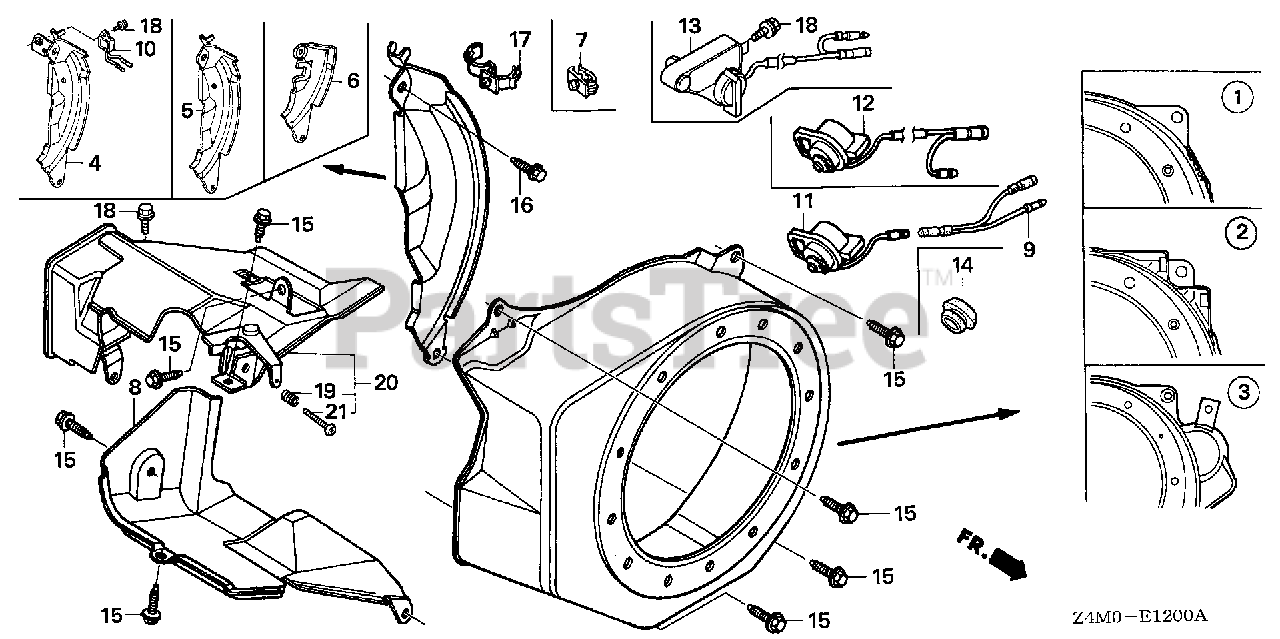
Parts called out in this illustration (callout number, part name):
1	COVER, FAN *NH1* (Honda Code 4212437). (BLACK)
1	COVER, FAN *R280* (Honda Code 7351950). (POWER RED)
4	PLATE, SIDE (OIL ALERT)
8	SHROUD
10	ALERT UNIT, OIL
12	SWITCH ASSY., ENGINE STOP
15	BOLT, FLANGE (6X12) (CT200)
16	BOLT, FLANGE (6X20) (CT200)
17	CLIP, HARNESS
18	BOLT, FLANGE (6X8)
